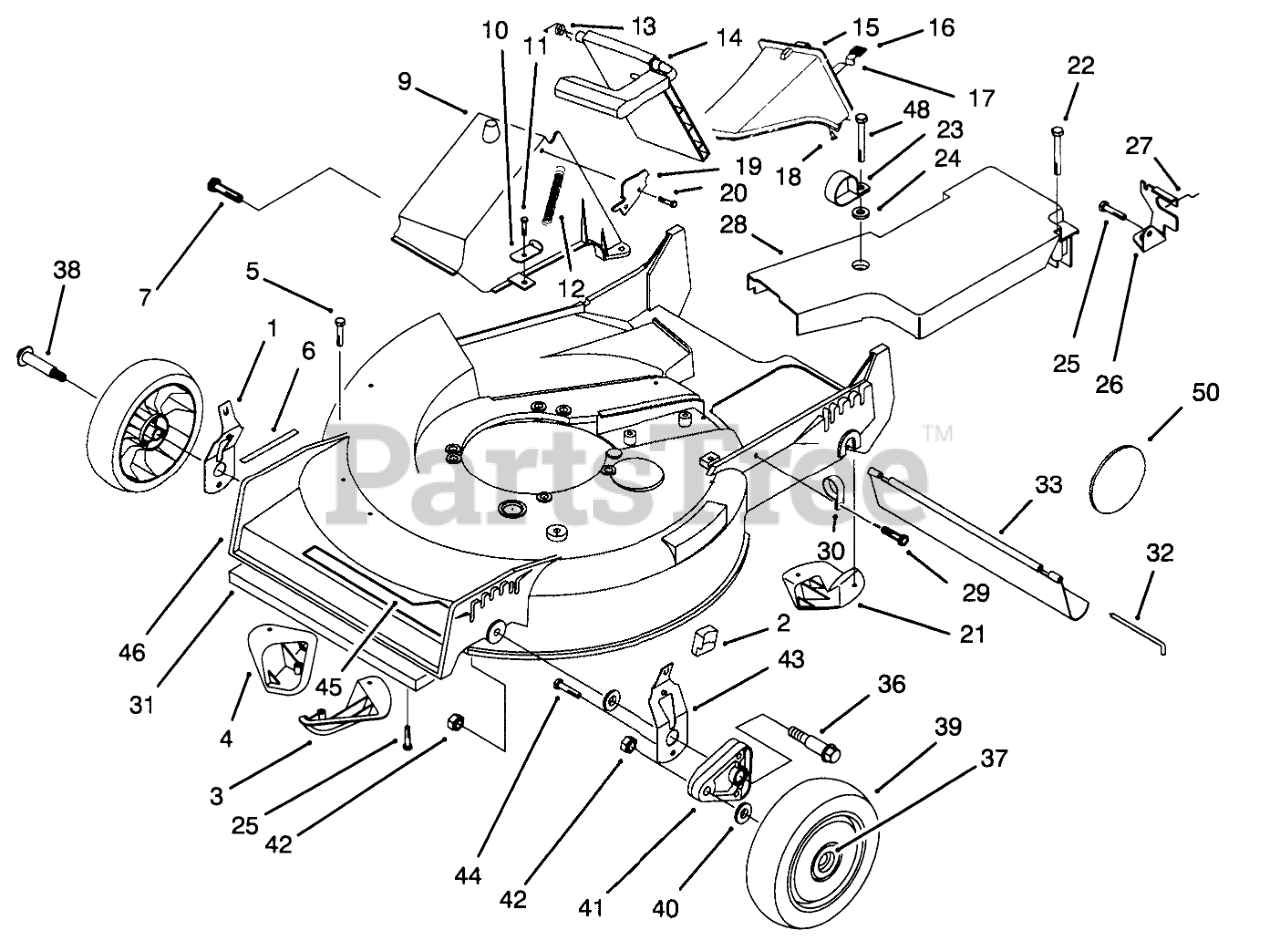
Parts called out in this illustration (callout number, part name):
1	RH SPRING ARM ASSEMBLY
2	KNOB-ARM
3	KICKER-FRONT
4	KICKER-RH
5	SCREW-PPH
6	DECAL - HOC
7	SCREW AND WASHER ASM
9	TUNNEL-DISCHARGE
10	BRACKET-SPRING
11	SCREW-HWH
12	SPRING-DOOR
13	RETAINER-DOOR
14	DOOR ASSEMBLY
15	Discharge Plug Assembly (Incl. Ref. #16-18)
16	GRIP-LATCH
17	LATCH-PLUG, DISCHARGE
18	RIVET-HEAD, FLAT
19	DOOR LATCH PLATE
20	SCREW-PLASTITE
21	KICKER-REAR
22	SCREW-HHFTF
23	CLAMP-CABLE
24	WASHER
25	SCREW-HWHTF
26	Bracket-Adj. Trac
27	RETAINER-CABLE
28	BELT COVER
29	SCREW-HWH
30	CLAMP-CABLE
31	Shield-front
32	ROD-SHIELD
33	SHIELD-TRAILING
36	BOLT-SHOULDER
37	BUSHING
38	BOLT-WHEEL
39	Wheel & Tire Assembly (Incl Ref. #37)
40	WASHER
41	ARM-PIVOT, FRONT
42	NUT-LOCK
43	LH SPRING ARM ASSEMBLY
44	SCREW-HWH
45	DECAL - DECK
46	Assembly (Incl. Ref. #3-6, & 21 pg.1) (Incl. Ref. #5 & 6 pg. 3)
48	SCREW-SPECIAL
50	COVER-WHEEL
